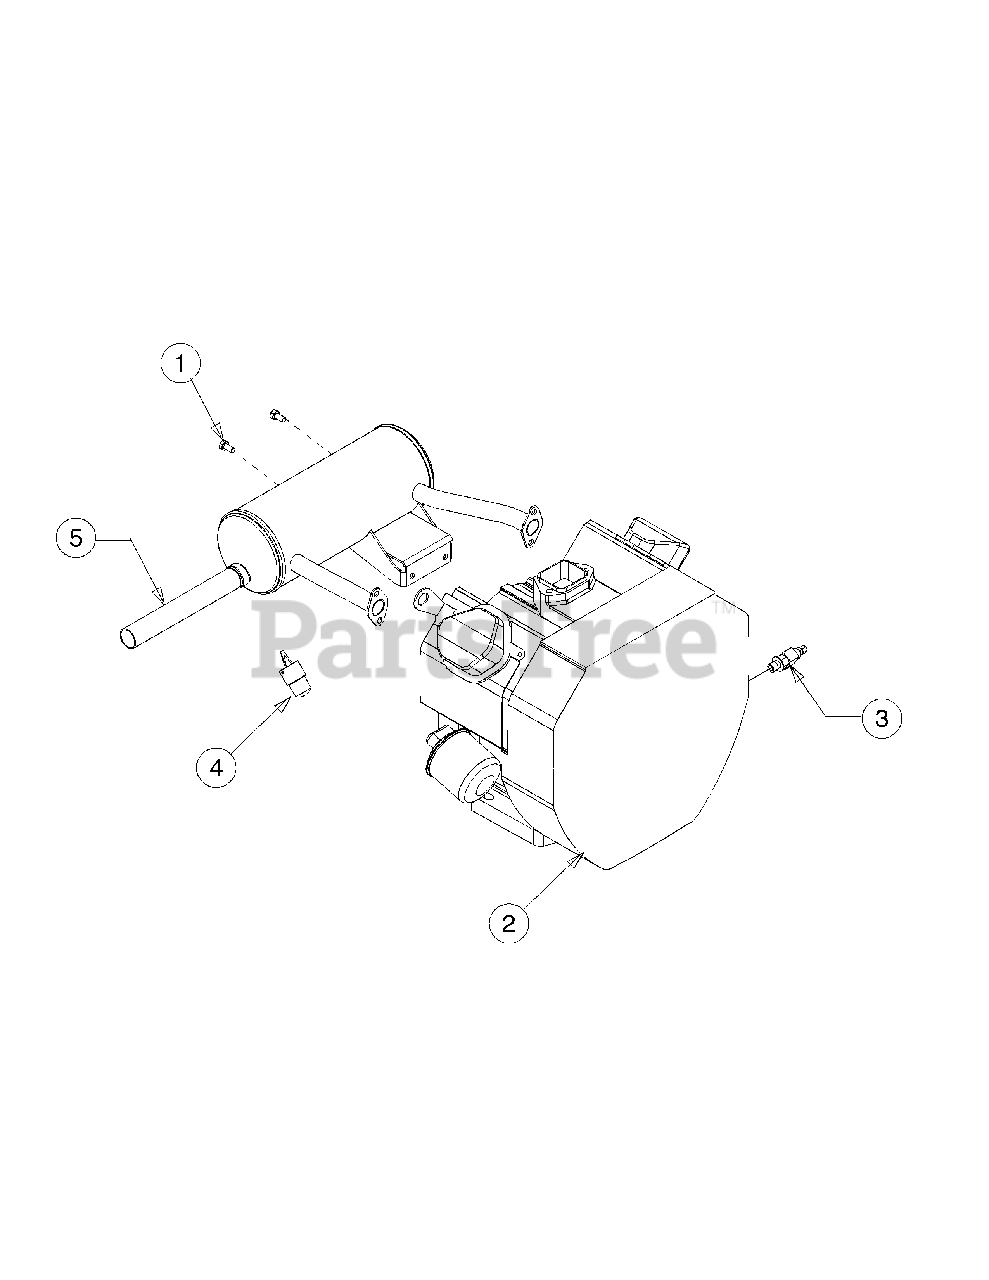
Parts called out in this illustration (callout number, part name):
1	Screw, M8
2	Engine, Honda GX618K1
3	Valve, Oil Drain
4	Spark Arrestor
5	Muffler, Honda GX620
